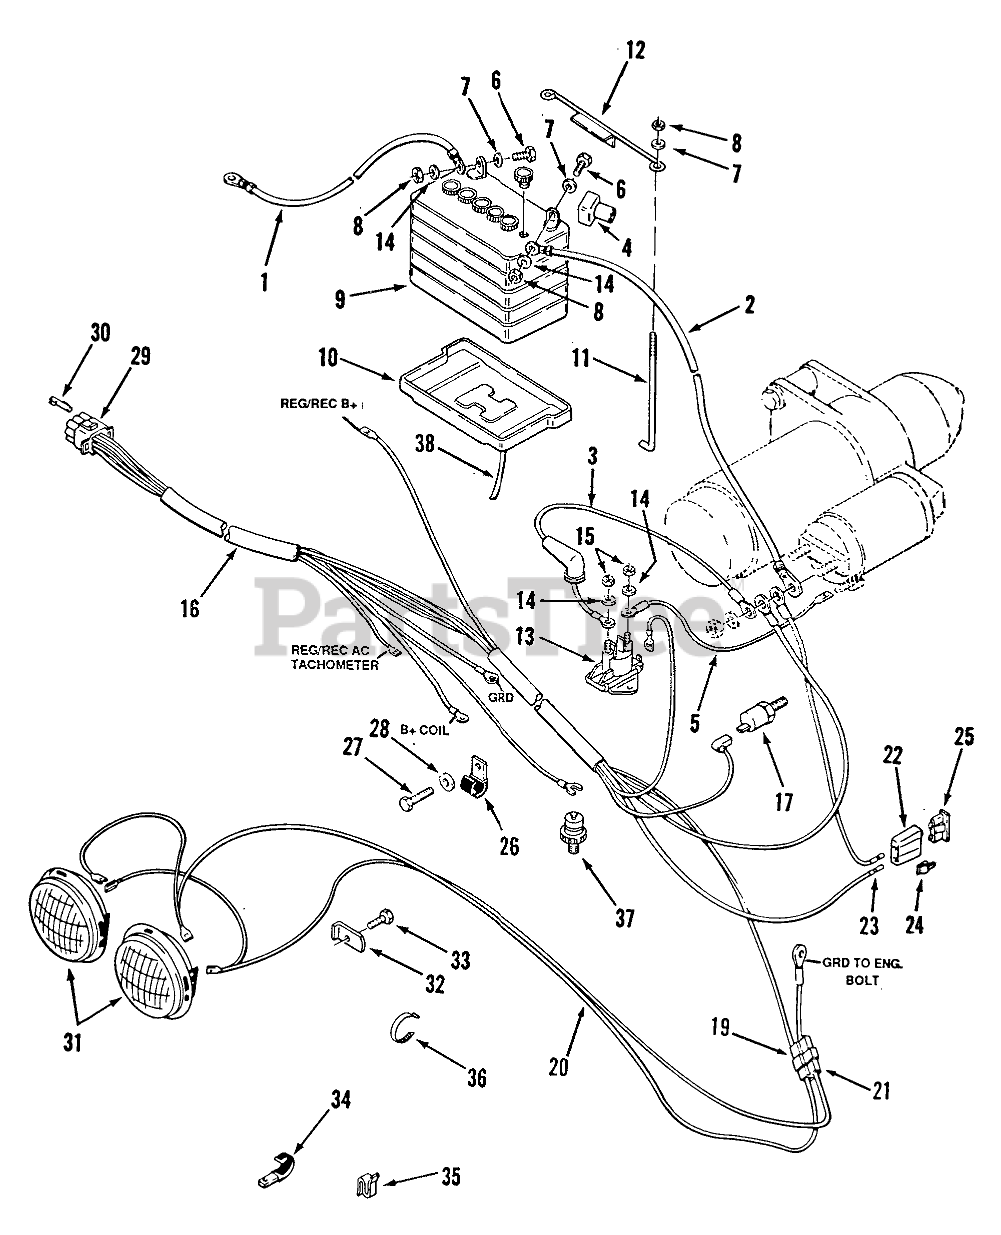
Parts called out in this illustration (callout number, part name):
1	ASS'Y-WIRE
2	ASS'Y-WIRE
3	ASS'Y-WIRE
4	Boot
5	ASS'Y-WIRE
6	Bolt
8	Nut
9	Battery
10	TRAY-BATTERY
11	HOOK-BATTERY RETAIN
12	HOLDDOWN-BATTERY
13	SOLENOID-STARTER
14	Washer
15	Nut
16	Engine Wiring Harness
17	HIGH TEMPERATURE
18	RECEPTACLE TERMINAL
19	MALE CONNECTOR
20	HARNESS-HEADLIGHT
21	CONNECTOR BODY
22	AUTO-FUSEBLOCK TERM
23	TERMINAL FUSE
25	FUSE-30 AMP
26	Clip
27	Bolt
28	LOCKWASHER 1/4 IT
29	CONNECTOR CAP
30	CONTACT SOCKET
31	HEADLAMP
32	LOCK-HEADLIGHT
33	Bolt
34	CLIP
35	SPEED CLIP
36	PLASTIC TIE
37	LOW OIL PRESSURE
38	TUBE-BATTERY DRAIN
53	WASHER
59	Wire-Switch to Engine
